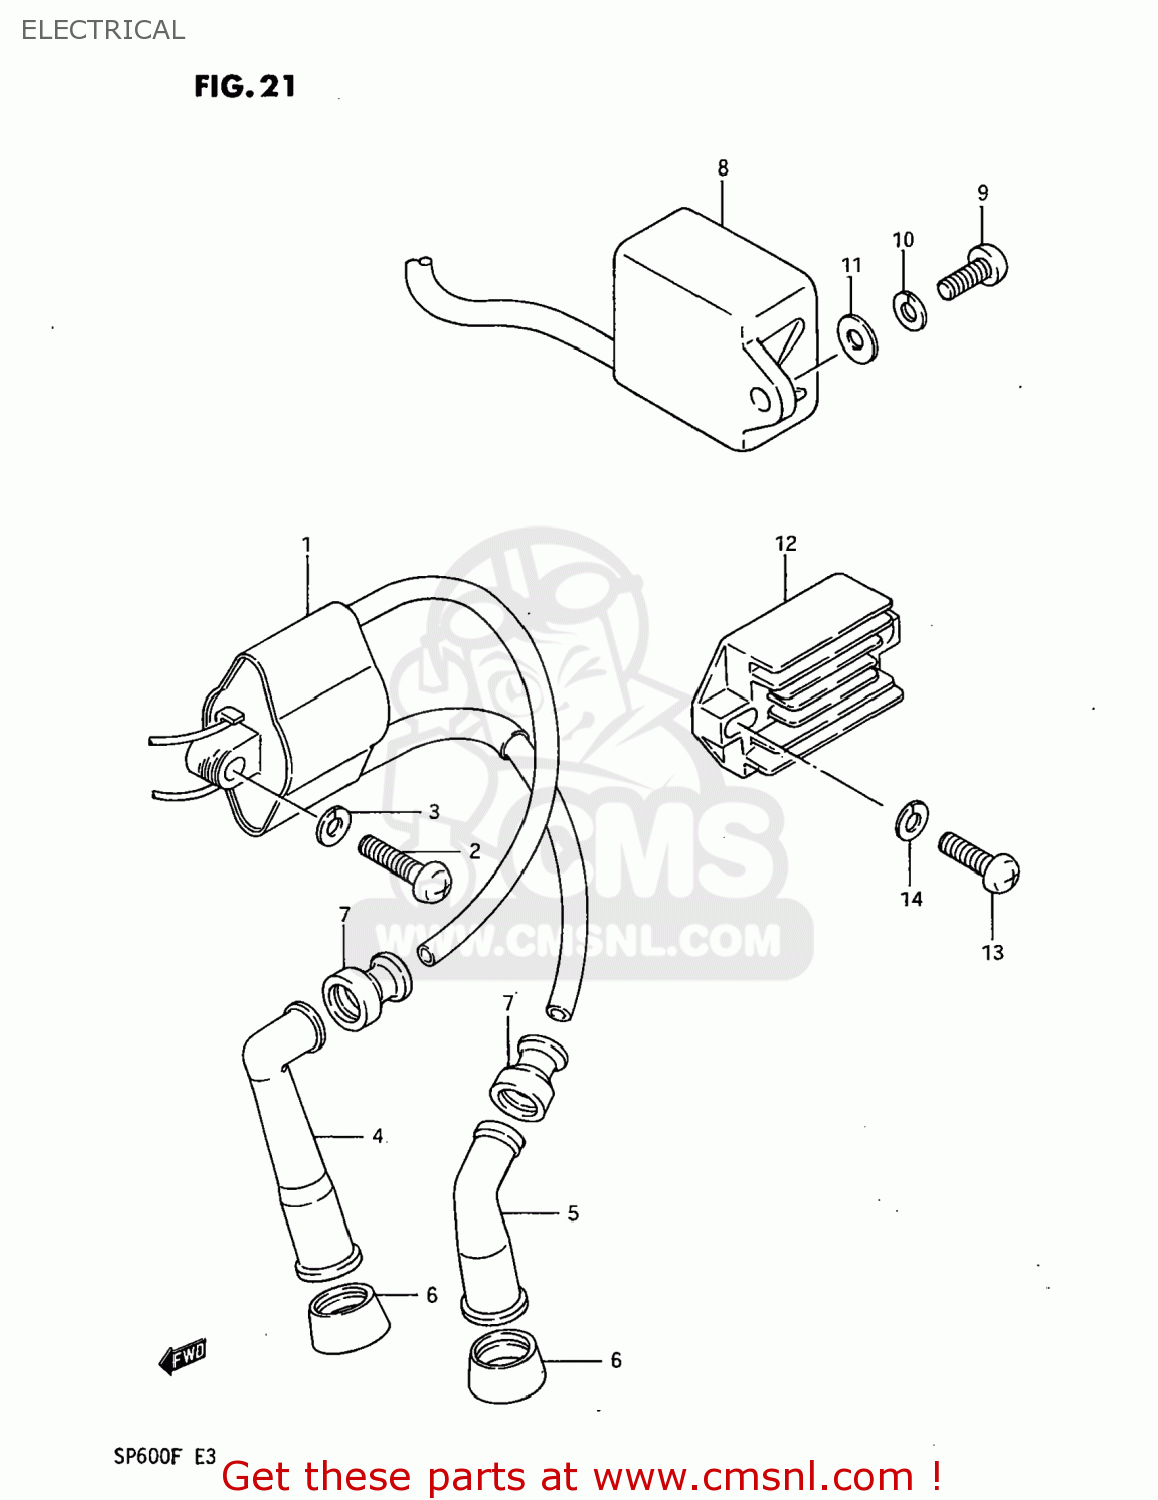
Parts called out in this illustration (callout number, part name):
1	COIL ASSEMBLY,IGNITION
2	SCREW
3	WASHER, LOWER
4	CAP ASSY,SPARK PLUG
5	CAP,SPARK PLUG
6	SEAL,SPARK PLUG CAP
7	SEAL,SPARK PLU
8	CDI UNIT
9	SCREW
10	WASHER,LOCK
11	WASHER, LOWER
12	RECTIFIER ASSEMBLY
13	SCREW
14	WASHER,LOCK
